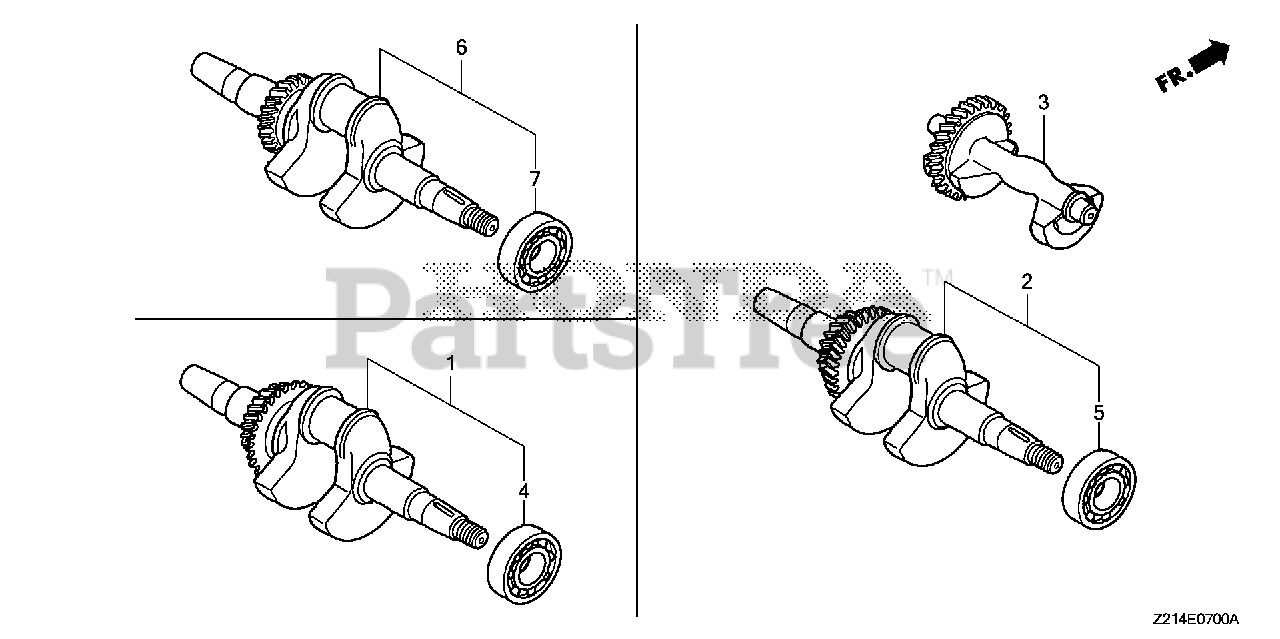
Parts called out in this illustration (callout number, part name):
2	CRANKSHAFT
3	WEIGHT, BALANCER
5	BEARING, RADIAL BALL (6207SH)
